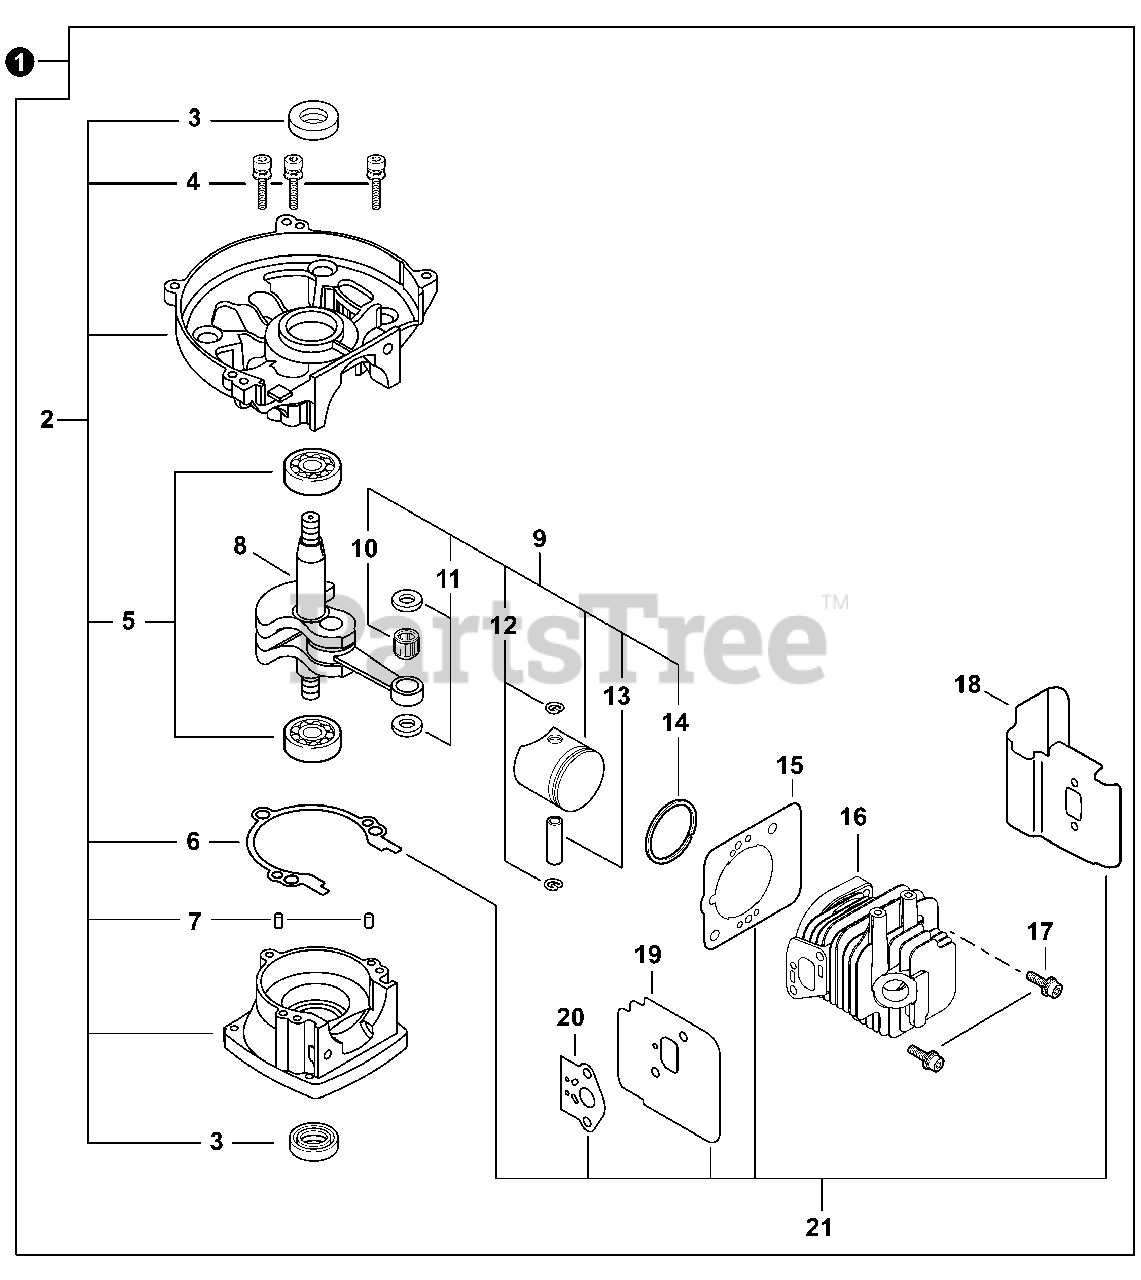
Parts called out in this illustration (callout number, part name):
1	SHORT BLOCK
2	CRANKCASE KIT
3	SEAL, OIL 12
4	BOLT 5×28
5	BEARING, BALL - 6201 C3
6	GASKET, CRANKCASE
7	PIN, LOCATING 4×8
8	CRANKSHAFT
9	PISTON KIT
10	BEARING, NEEDLE
11	WASHER, THRUST
12	RING, SNAP
13	PIN, PISTON 8
14	RING, PISTON
15	GASKET, CYLINDER
16	CYLINDER
17	BOLT 5×22
18	HEAT SHIELD, EXHAUST
19	HEAT SHIELD, INTAKE
20	GASKET, INTAKE
21	GASKET KIT
